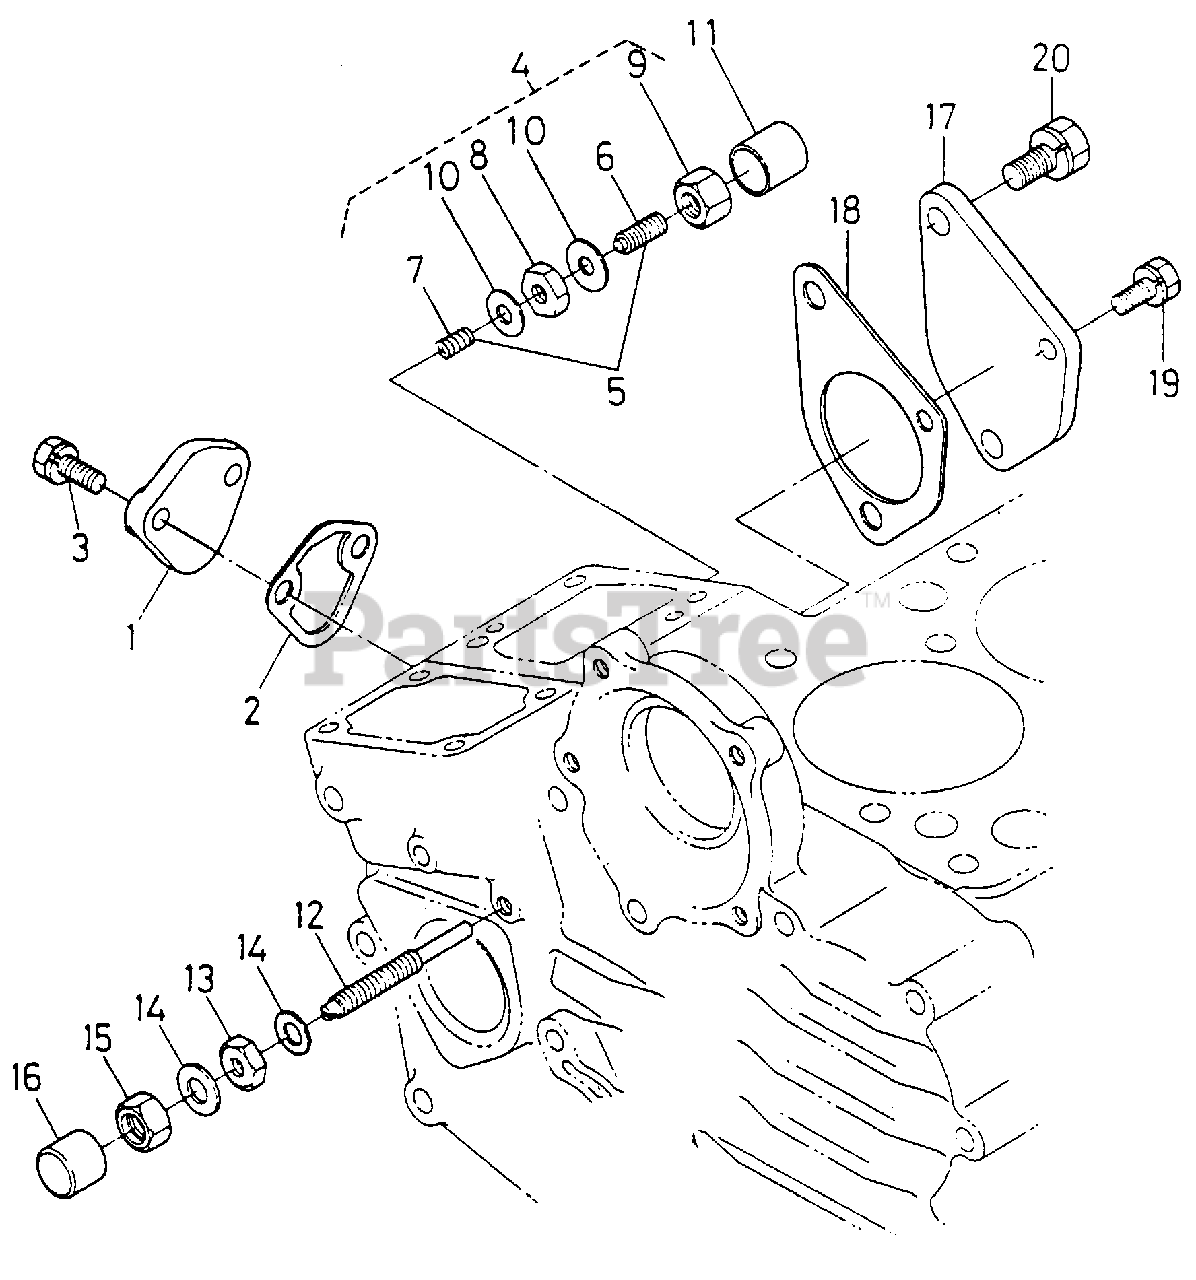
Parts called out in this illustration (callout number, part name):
3	Bolt, M6 X 16 Class 8.8 w/Washer
4	Bolt Assy, Idling
5	Bolt Assy, Adjusting
12	Bolt, Adjusting
19	Bolt, M6 X 16 Class 8.8 w/Washer
20	Bolt, M8 X 18 Pln Class 8.8
